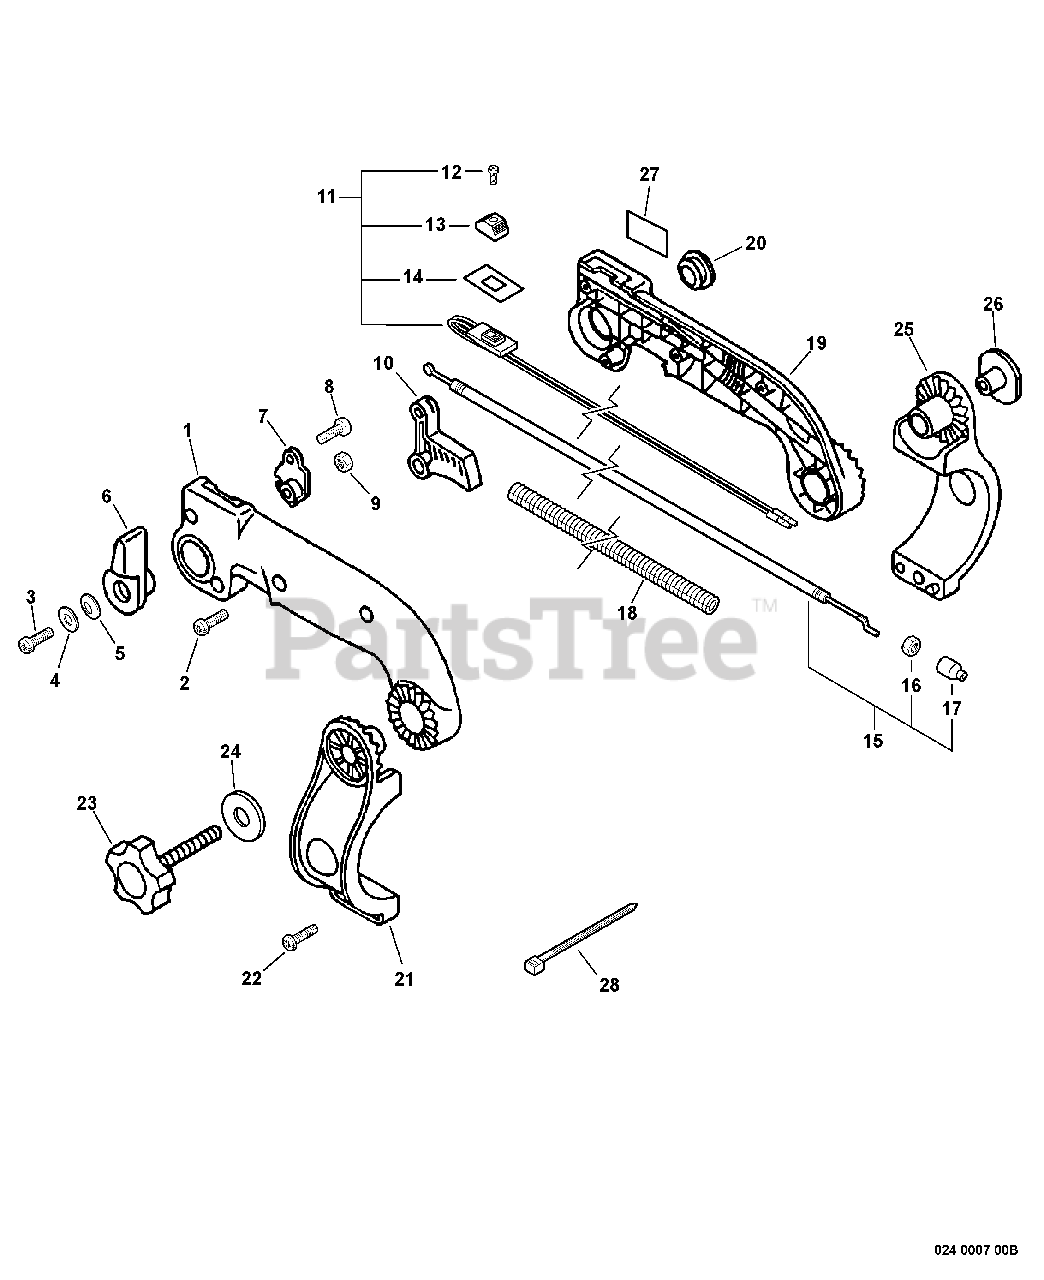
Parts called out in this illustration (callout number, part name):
1	HANDLE, CONTROL - LEFT
2	SCREW - 4X22
3	SCREW - 6X20
4	LOCKWASHER - 6
5	WASHER - 6
6	CONTROL, THROTTLE
7	BRACKET, THROTTLE
8	SCREW - 4X10
9	LOCKNUT - 6
10	TRIGGER, THROTTLE
11	IGNITION SWITCH ASSY
12	SCREW - 3X10
13	KNOB, SWITCH - ORANGE
14	COVER, SWITCH - STOP
15	CABLE, THROTTLE
16	LOCKNUT - 6
17	CAP, DUST
18	TUBE, PROTECTIVE - CORRUGATED
19	HANDLE, CONTROL - RIGHT
21	BRACKET, HANDLE - LEFT
22	SCREW - 5X20 -- TAPPING
23	THUMBSCREW
24	WASHER - 6
25	BRACKET, HANDLE - RIGHT
27	LABEL - STOP
28	TIE, CABLE - SMALL
